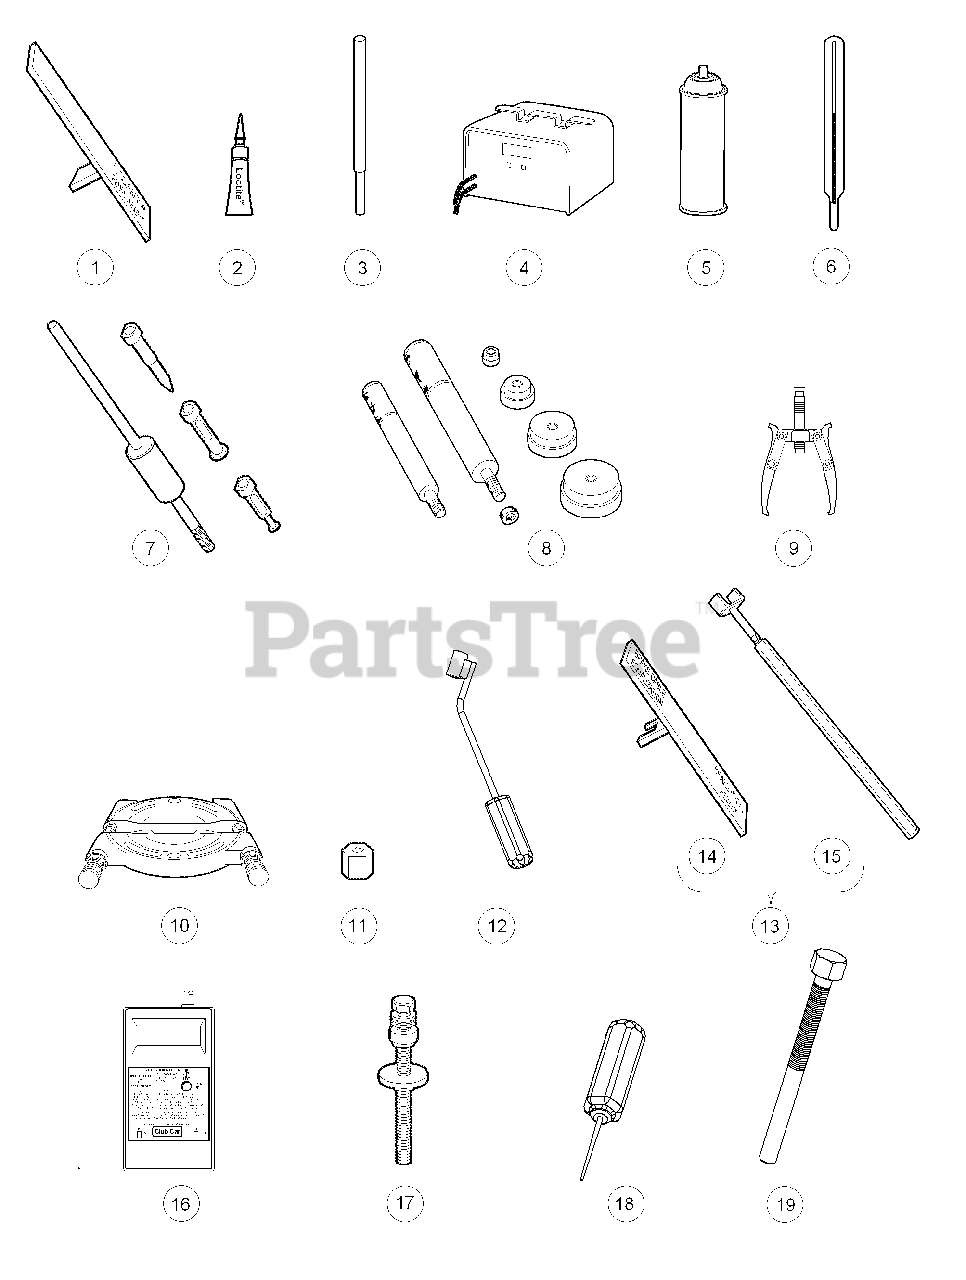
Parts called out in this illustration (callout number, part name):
1	Accelerator Pedal Adjustment Tool
2	Adhesive, Guide Ring, 3-Gram Tube
4	Battery Discharge Machine, 36/48 Volt
5	Battery Terminal Protector Spray
6	Battery Thermometer
7	Bearing and Oil Seal Remover Assembly
8	Bearing Driver Set
9	Bearing Puller
10	Bearing Puller Wedge Attachment
11	Brake Adjustment Tool
12	Brake Cable Release Tool
13	Brake Pedal Adjustment Tool Kit
14	Brake Pedal Adjustment Tool
15	Brake Pedal Tension Tool
16	Calibration Test Module
17	Cam Installation Tool
18	Charger Bezel Tool
19	Clutch Removal Tool
